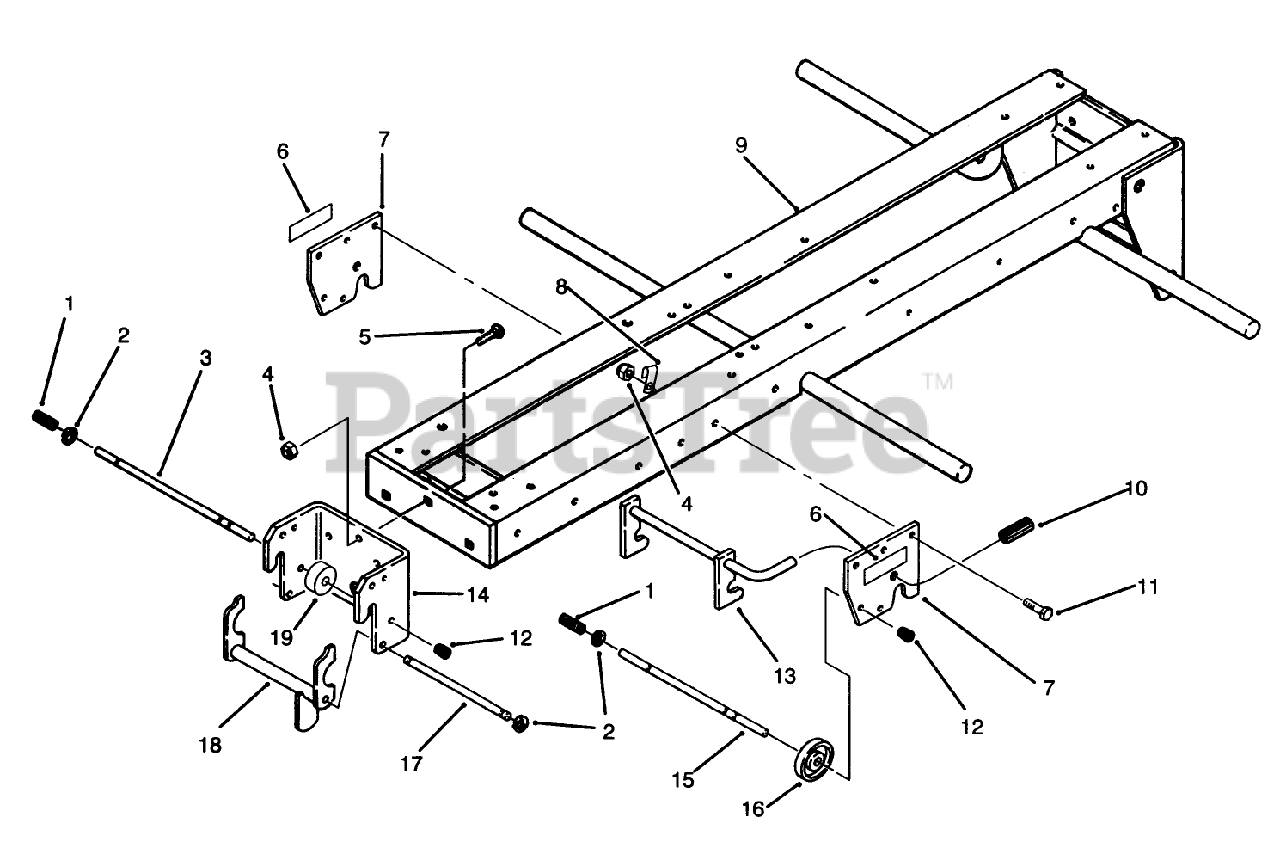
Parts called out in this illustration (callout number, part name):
1	SPRING
2	RING-RETAINING
3	ROD-LOCK
4	NUT-LOCK, NI
5	BOLT-CARR
6	DECAL-ATTACH A-MATIC
8	CLIP
10	GRIP
11	SCREW-HH
12	CAP-ROD, PLUNGER
13	MID HITCH ASM
15	ROD-LOCK
17	ROD-LATCH PIVOT
18	LATCH
